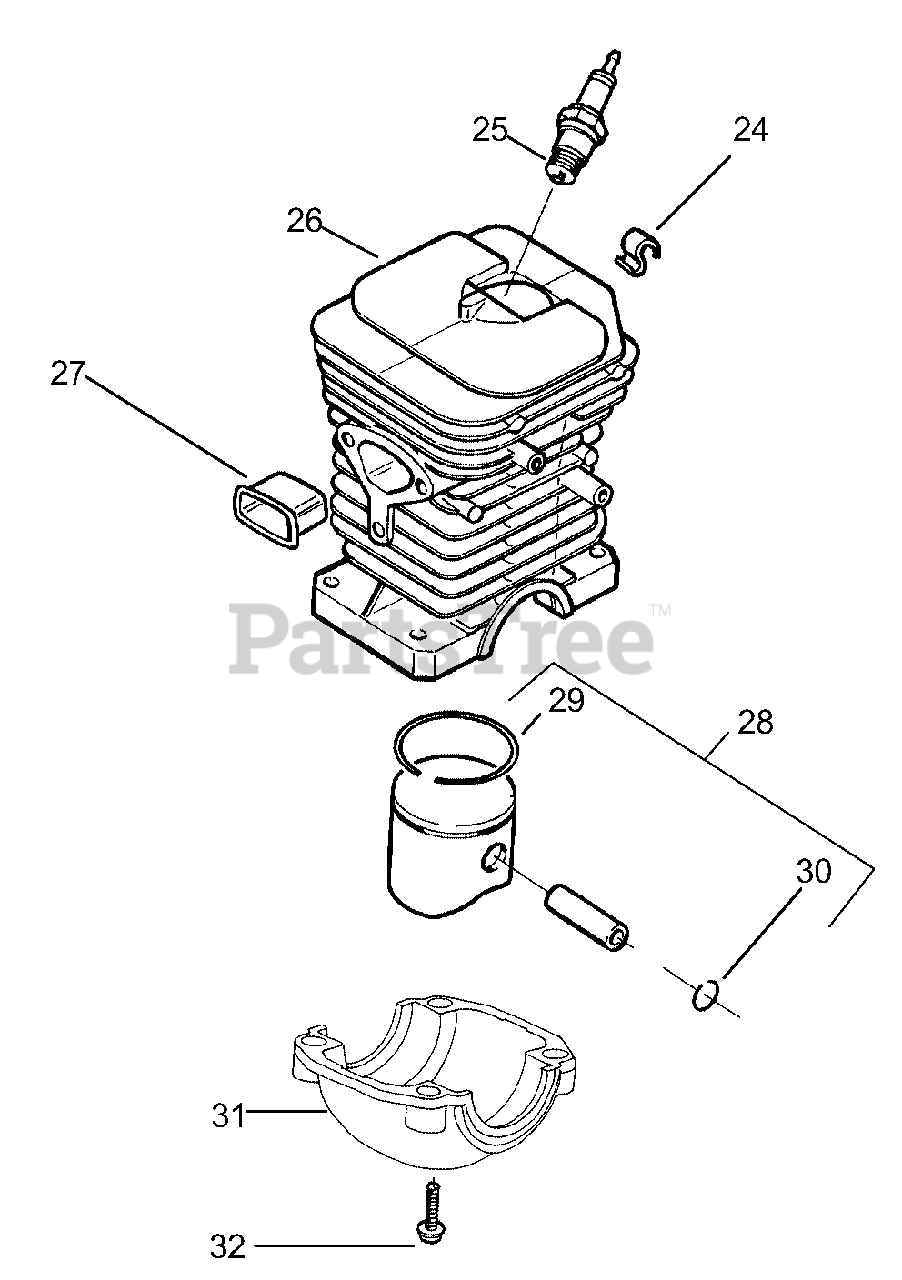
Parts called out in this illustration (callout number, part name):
25	Spark Plug (RCJ-7Y)
26	Kit-Cylinder
27	Insulator-Heat
28	Piston Kit
29	Ring-Piston (36cc)
30	Piston Pin Retainer
31	Cap-Crankcase
